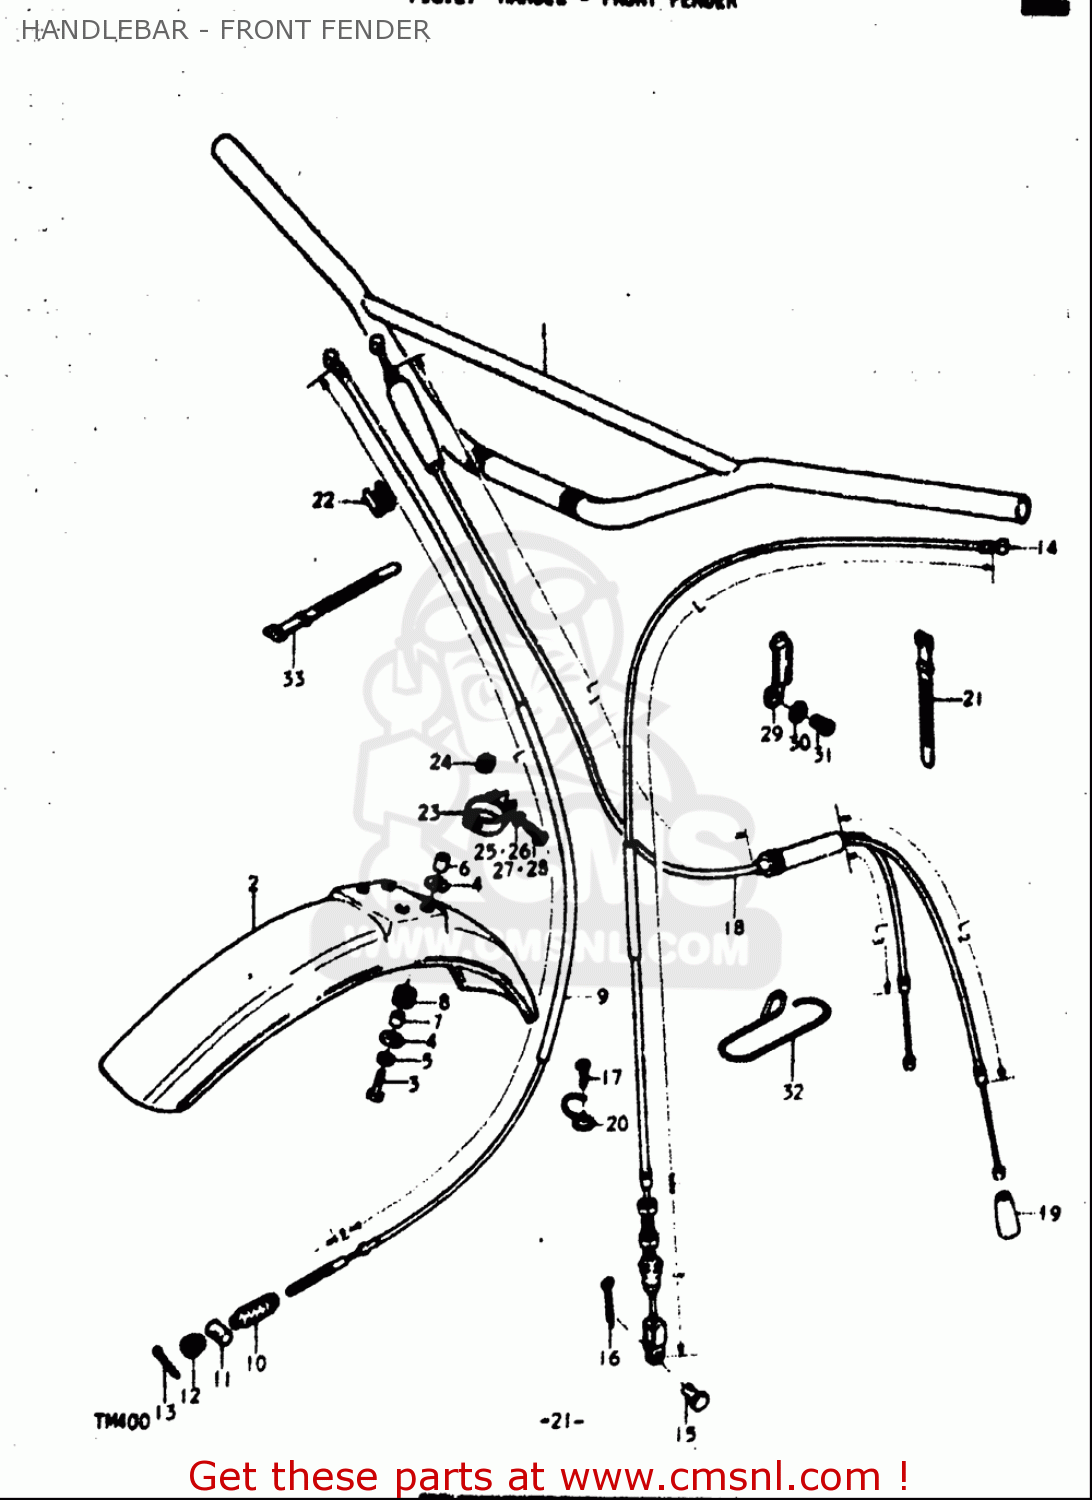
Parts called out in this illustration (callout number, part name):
3	BOLT
4	WASHER(6.5X24X1.2)
5	WASHER,LOCK
7	SPACER(6.5X10X13.5)
8	CUSHION
10	SEAL,DUST
11	PIN(13X18)
12	NUT
13	PIN
14	WIRE,CLUTCH
15	PIN(L:15)
16	PIN
17	SCREW
18	CABLE ASSY,THROTTLE
19	SEAL,DUST(7X18X30)
20	CLIP
22	CLIP
24	CUSHION
25	WASHER,LOCK
26	WASHER
27	SCREW
28	SCREW 4X16
30	WASHER,LOCK
31	SCREW
33	CLAMP
